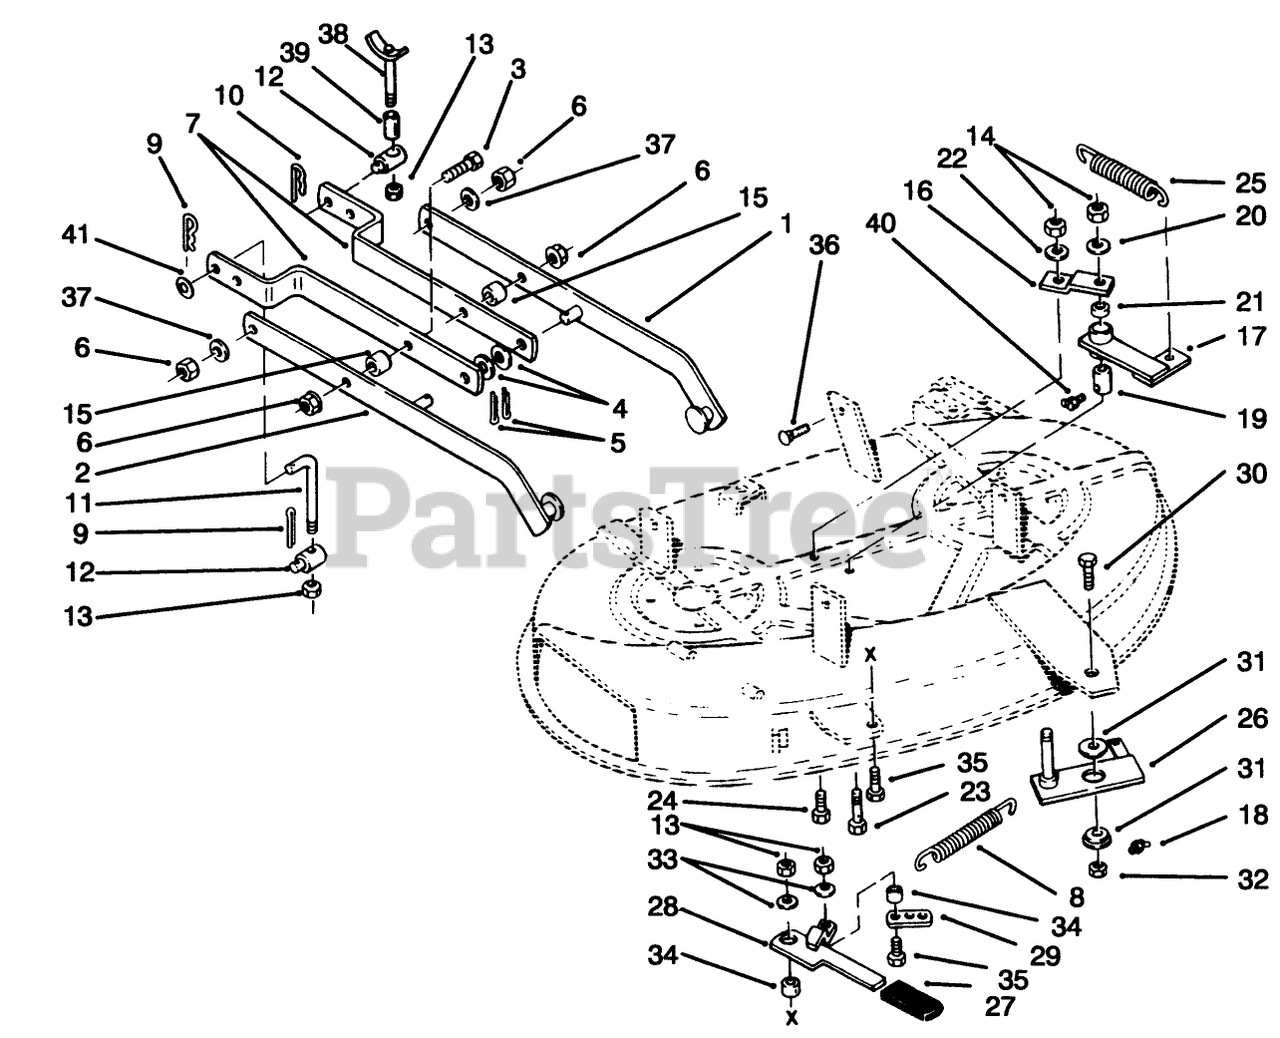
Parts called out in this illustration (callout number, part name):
1	Draft Bar LH
2	Draft Bar RH
3	SCREW-HH
4	WASHER-FLAT
5	PIN-COTTER
6	LOCKNUT-FLANGE
7	Bar-Leveler
8	Spring
9	PIN-COTTER
10	Hairpin
11	ROD-LIFT
12	TRUNNION
13	NUT-LOCK, NI
14	NUT-LOCK, NI
15	SPACER
16	Strap
17	Arm-Idler
18	Fitting-Grease
19	SPACER-2.0 LG R
21	BUSHING
22	WASHER-PLAIN
23	SCREW-HH
24	SCREW-HH
25	SPRING
26	Countershaft
28	Lever
29	Link
30	Bolt
31	BUSHING
32	NUT-LOCK, NI
33	WASHER
34	SPACER
35	SCREW-HH
36	BOLT-CARR
37	SPACER
38	WLDMT-HANGER ROD
39	SPACER .375 ID X 1.6
40	FITTING-GREASE
41	WASHER-PLAIN
